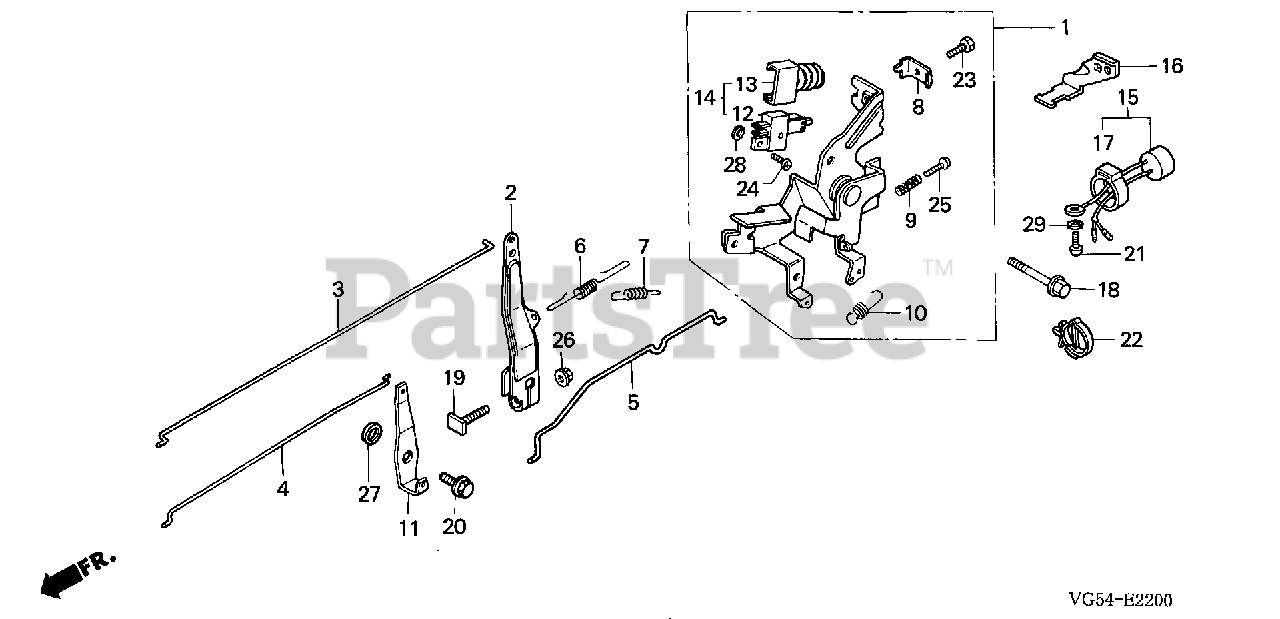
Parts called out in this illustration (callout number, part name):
1	CONTROL ASSY.
2	ARM, GOVERNOR
3	ROD, GOVERNOR
4	ROD, CHOKE
5	ROD, JOINT
6	SPRING, GOVERNOR
7	SPRING, GOVERNOR PRIMARY
8	HOLDER, CABLE
9	SPRING, CONTROL ADJUSTING
10	SPRING, CABLE RETURN
11	LEVER, CHOKE JOINT
12	SWITCH ASSY., ENGINE
13	COVER, SWITCH
14	SWITCH ASSY., ENGINE STOP
15	BUZZER ASSY.
16	STAY, BUZZER
17	SUSPENSION, AUDIBLE PILOT
18	BOLT, FLANGE (6X12) (CT200)
19	BOLT, GOVERNOR ARM
20	BOLT, FLANGE (6MM)
21	SCREW, TAPPING (5X8)
22	CLIP, WIRE HARNESS
23	BOLT, RECESSED (5X16)
24	SCREW, PAN (4X14)
25	SCREW, PAN (5X20)
26	NUT, FLANGE (6MM)
27	WASHER, PLAIN (6MM)
28	WASHER, SPRING (4MM)
29	WASHER, SPRING (5MM)
